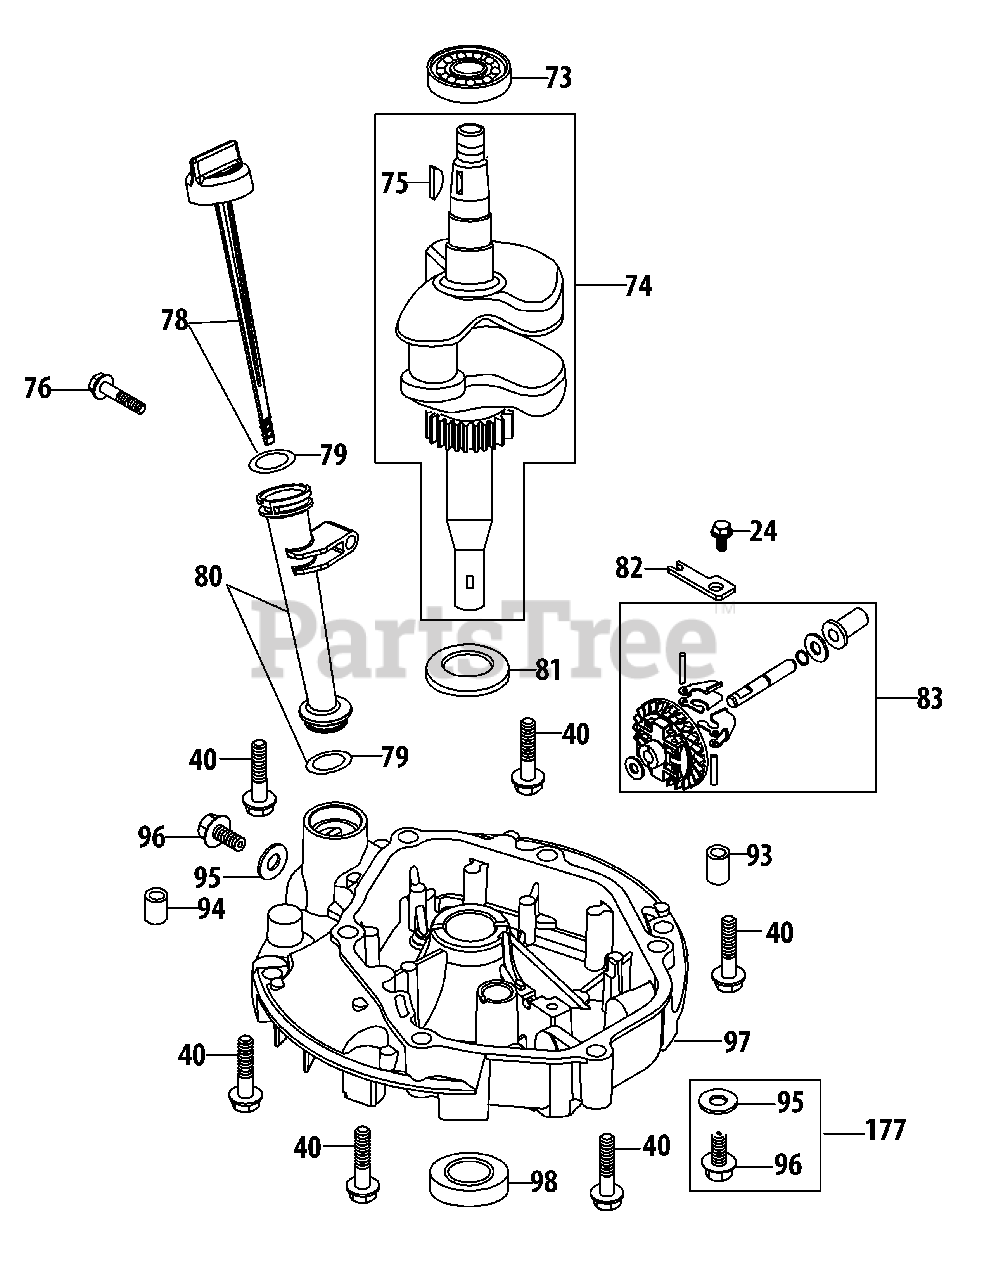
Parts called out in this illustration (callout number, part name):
24	Bolt M6X14
40	Bolt M8X50
73	Main Bearing
74	Crankshaft Assembly
75	Woodruff Key
76	Bolt M6X35
78	Dipstick Assembly
79	Dipstick / Oil Fill Tube O-Ring
80	Oil Filler Tube Assemlby
81	Crankshaft Thrust Washer
82	Governor Gear Mounting Plate
83	Governor Gear/Shaft Assembly
93	Crankcase Cover Dowel Pin 7×14
94	Crankcase Cover Dowel Pin 9×14
95	Oil Drain Plug Washer
96	Oil Drain Plug
97	Crankcase Cover
98	Lower Crankshaft Seal
177	Oil Drain Plug And Washer Assy
